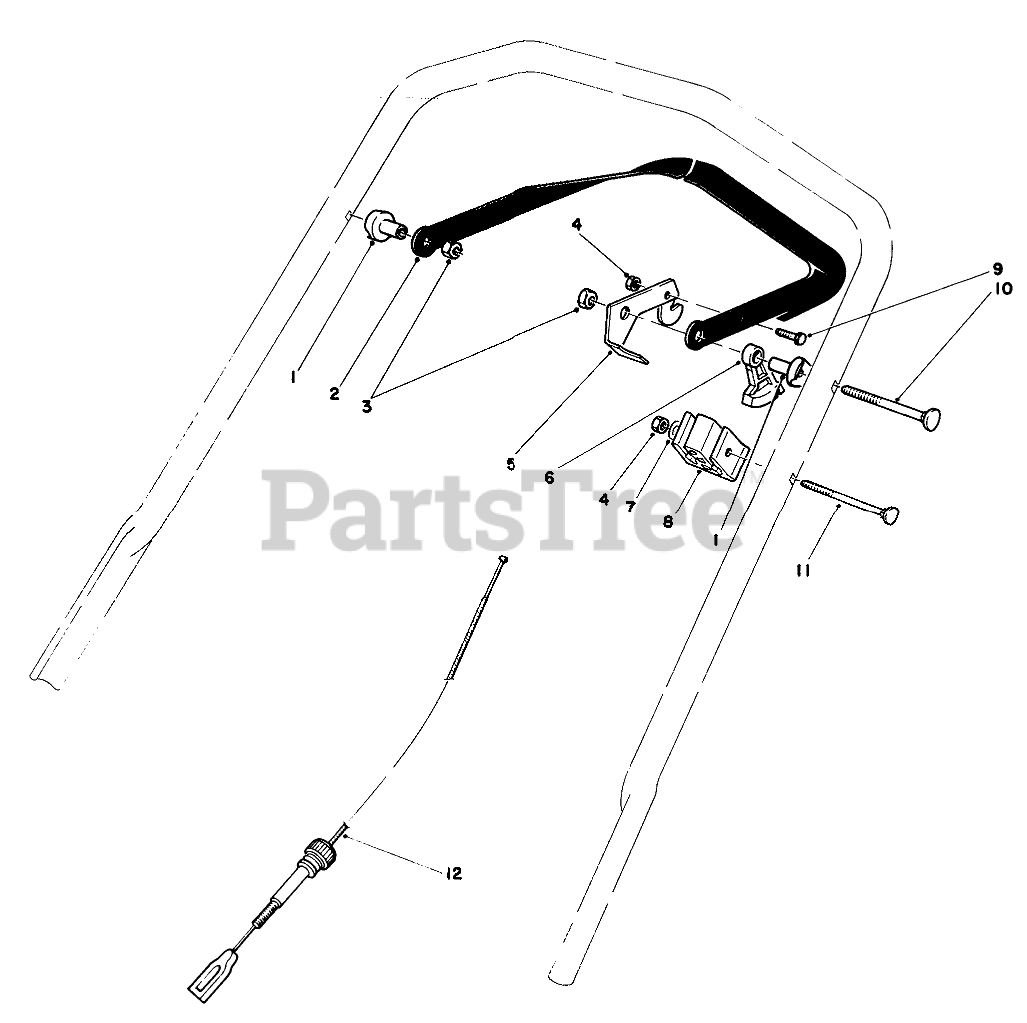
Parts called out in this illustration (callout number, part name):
1	SPACER-SUPPORT
2	Bar-Control
3	NUT-LOCK, NI
4	NUT-LOCK, NI
5	CONTROL LEVER
6	LEVER-TRACTION
7	WASHER-FLAT
8	SUPPORT-CABLE
9	SCREW-HH
10	5/16-18 X 2 HNDLE SCREW
11	SCREW-HANDLE
12	CABLE-TRACTION
